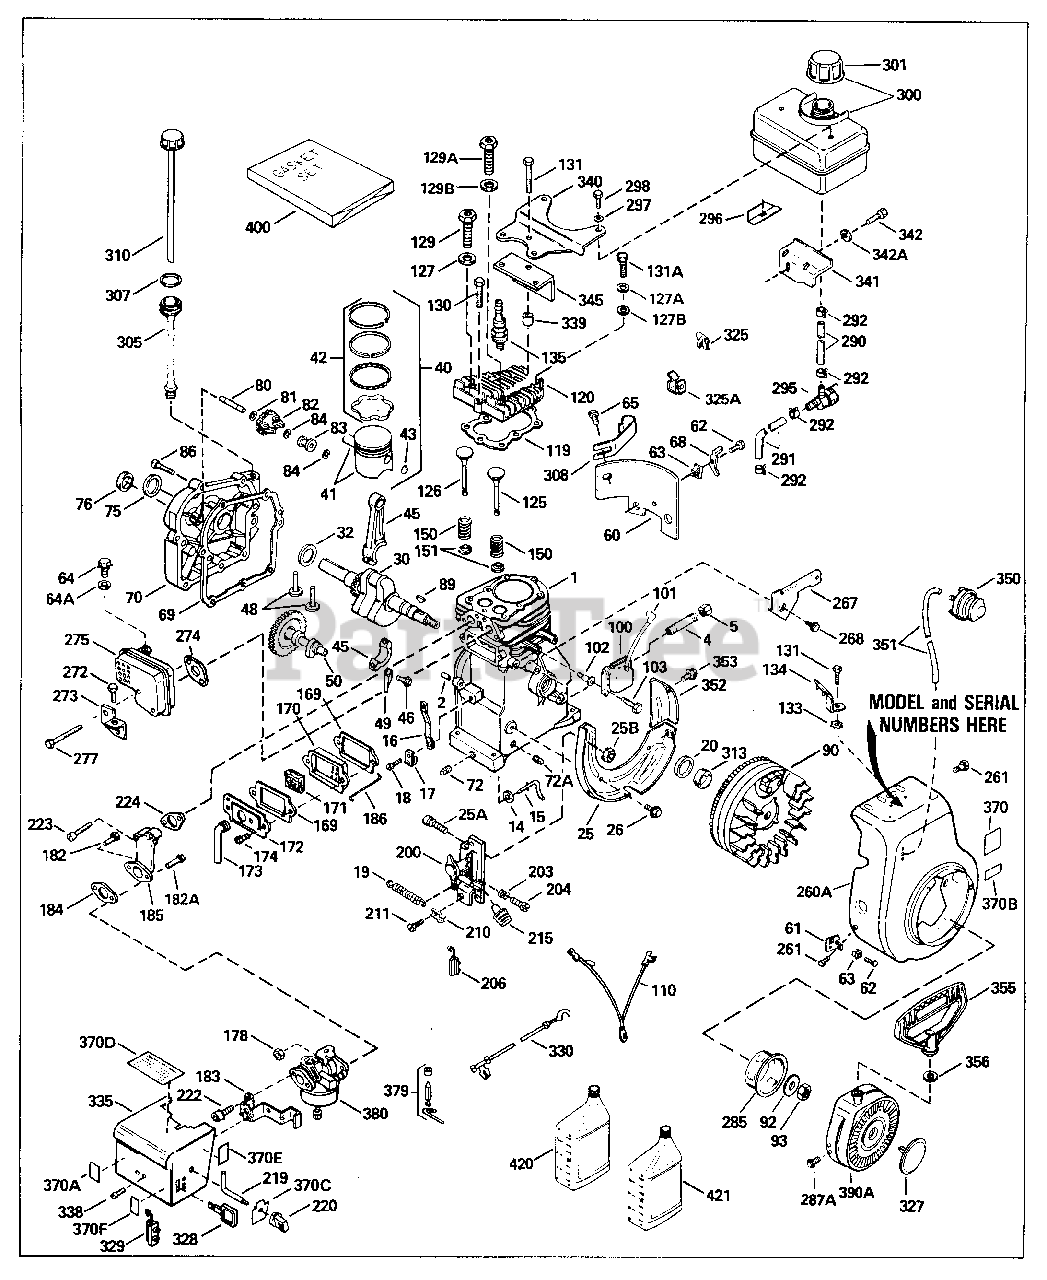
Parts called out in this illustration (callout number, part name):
1	"Cylinder (Incl. 2, 20, 72 & 72A)
2	Dowel Pin
14	Flat Washer
15	Rod, Governor
16	Lever, Governor
17	Clamp, Governor lever
18	Screw, 8-32 x 5/16"
19	Spring, Extension
20	Seal, Oil
25	Baffle, Blower housing
25A	Screw, 8-32 x 1/2" (Use as required)
25B	Lock Nut, 8-32
26	Screw, 1/4-20 x 5/8"
30	Crankshaft
32	Washer, Thrust NOTE: This thrust wash er maynot be required if a new cranks hafthas been installed. Check the pro per Mechanic's Handbook for acceptabl e end play. Use this .010" thrust was her if excess end play is measured.
40	Piston, Pin & Ring Set (Std.)
40	Piston, Pin & Ring Set (.010" OS)
40	Piston, Pin & Ring Set (.020" OS)
41	Piston & Pin Ass'y. (Std.) (Incl. 43)
41	Piston & Pin Ass'y. (.010" OS) Incl. 43
41	Piston & Pin Ass'y. (.020" OS) Incl. 43
42	Ring Set (Std.) (2-13/16" Bore)
42	Ring Set (.010" OS)
42	Ring Set (.020" OS)
43	Piston Pin Retaining Ring
45	Rod Assy., Connecting (Incl. 46 & 49)
46	Bolt, Connecting rod
48	Valve Lifter
49	Dipper, Oil
50	Camshaft (Extended)
60	Blower Housing Extension
61	Bracket, Grommet mounting
62	Screw, 8-32 x 3/8"
63	Breather Tube Grommet
64	Screw, T-30, 1/4-20 x 1/2"
64A	Washer, Flat
65	Screw, 10-24 x 1/2"
69	* Gasket, Cylinder cover
70	Cover, Cylinder (Incl. 75, 76 & 80)
72	Oil Drain Plug (Sq. hd., 1/4-18)
75	Oil Seal
76	Camshaft Seal
80	Shaft, Mechanical governor
81	Washer, Flat
82	Gear, Governor
83	Spool, Governor
84	Retaining Ring
86	Screw, 1/4-20 x 1-1/4"
89	Flywheel Key (also available in Packa ged Part #740007B)
90	Flywheel (w/ring gear)
92	Washer, Belleville
93	Nut, Flywheel
100	Solid State Assy.
101	Cover, Spark plug
102	Stud, Solid state mounting
103	Screw, Torx T-15, 10-24 x 1"
110	Ground Wire
119	* Gasket, Cylinder head
120	Head, Cylinder (Incl. 131)
125	Exhaust Valve (Std.) (Incl. 151)
125	Exhaust Valve (1/32" OS) (Incl. 151)
126	Intake Valve (Std.) (Incl. 151)
126	Intake Valve (1/32" OS) (Incl. 151)
127	Washer, Flat
129	Screw, 5/16-18 x 1-1/2"
130	Screw, 5/16-18 x 1-1/2"
131	Screw, 5/16-18 x 2"
135	Resistor Spark Plug - RJ17LM
150	Spring, Valve
151	Cap, Valve spring
171	Element, Breather
174	Screw, 10-24 x 1/2"
178	Nut & Lock Washer 1/4-28
182	Screw, 1/4-28 x 7/8"
182A	Screw, 1/4-28 x 1-11/16"
183	Bracket, Choke
184	* Gasket, Carburetor
185	Pipe, Intake
186	Link, Governor to throttle
200	Control Bracket (Incl. 25A, 25B, 204 & 206) NOTE: In original production the speed control assembly may be riv eted to the blower housing baffle. Re placement speed control includes scre ws (650139) and nuts (30322) for moun ting. Replacement baffl
203	Spring, Compression
204	Screw, 5-40 x 7/16"
206	Terminal Assy.
210	Conduit Clip
215	Control Knob
219	Rod, Choke
220	Control Knob
222	Screw, 10-32 x 1/2"
223	Screw, 1/4-20 x 1-19/32"
224	* Gasket, Intake pipe
261	Screw, 1/4-28 x 7/16"
267	Bracket, Hold down
268	Screw, 10-24 x 9/16"
272	Screw, 10-24 x 3/8"
273	Bracket, Carburetor cover
274	* Gasket, Exhaust
275	Muffler (Incl. 274)
277	Screw, 1/4-20 x 2-1/2"
285	Cup, Starter
291	Fuel Line (16") (40cm)
292	Fuel Line Clamp
298	Screw, 1/4-15 x 7/8"
300	Fuel Tank (Incl. 292 & 301) NOTE: The se tanks were builtwith different siz e fuel inlet openings. Tanks with the 1-3/16" I.D. opening use fuel cap 34 210. Tanks with the 1-1/2" I.D. openi ng use fuel cap 35355.
301	Fuel Cap
305	Tube, Oil fill
307	"O" Ring
310	Dipstick (Incl. 307)
313	Spacer, Flywheel key
335	Cover, Carburetor
338	Screw, 8-32 x 5/16"
340	Fuel Tank Bracket
341	Fuel Tank Bracket
342	Screw, 1/4-20 x 11/16"
342A	Washer, Flat
345	Baffle, Heat
350	Primer Assy.
351	Line, Primer
352	Extension, Baffle
353	Screw, 8-32 x 1/2"
355	Starter Handle (Mitten Grip) also ava ilable in Packaged Part #740053B
356	Washer, Flat
370	Decal, Instruction
370A	Decal, Instruction
370B	Decal, Primer
370C	Decal, Choke
370D	Decal, Warning
370E	Throttle Decal
379	Inlet Needle, Seat & Clip Assy.
380	Carburetor (Incl. 184) (Refer to Divi sion 5, Section A, page 168 for break down)
400	* Gasket Set (Incl. items marked *)
420	SAE 30, 4-Cycle Engine Oil (Quart)
421	SAE 5W30 4-Cycle Engine Oil - Quart - Winter
